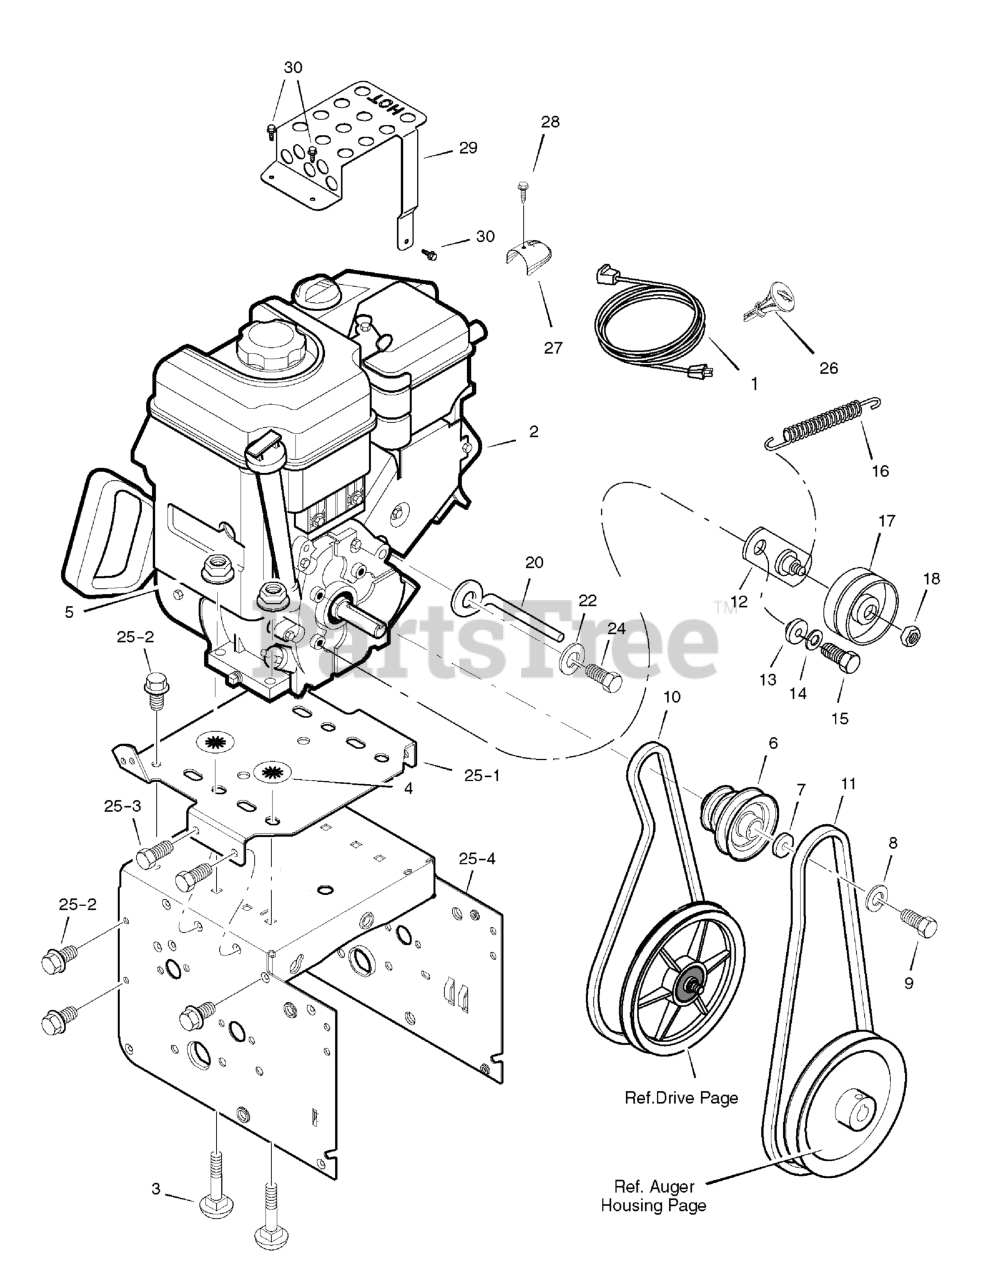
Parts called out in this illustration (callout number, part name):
1	CORD, Electric, 10FT. 110V
2	ENGINE *
3	BOLT, Carriage
4	RETAINER, Push
5	NUT
6	PULLEY, Engine
8	WASHER, Flat
9	BOLT, Hex 5/16-24 x 1
10	V-BELT, Drive, 4L
11	V-BELT, Auger, 3L
12	BRACKET ASSEMBLY, Idler
13	BUSHING, Idler Bracket
14	WASHER, Split
15	SCREW, 5/16-24 x 3/4
16	SPRING, Idler Traction Drive
17	PULLEY, Idler
18	NUT, Jam, 3/8 - 16
20	GUIDE, Rod Belt
22	WASHER
25	FRAME ASSEMBLY
25-1	PLATE, Engine
25-2	SCREW
25-4	MOTOR BOX
26	KEY, Briggs Engine
27	DEFLECTOR, Muffler
29	HEAT SHIELD, Muffler
30	SCREW, Hex-Washer
